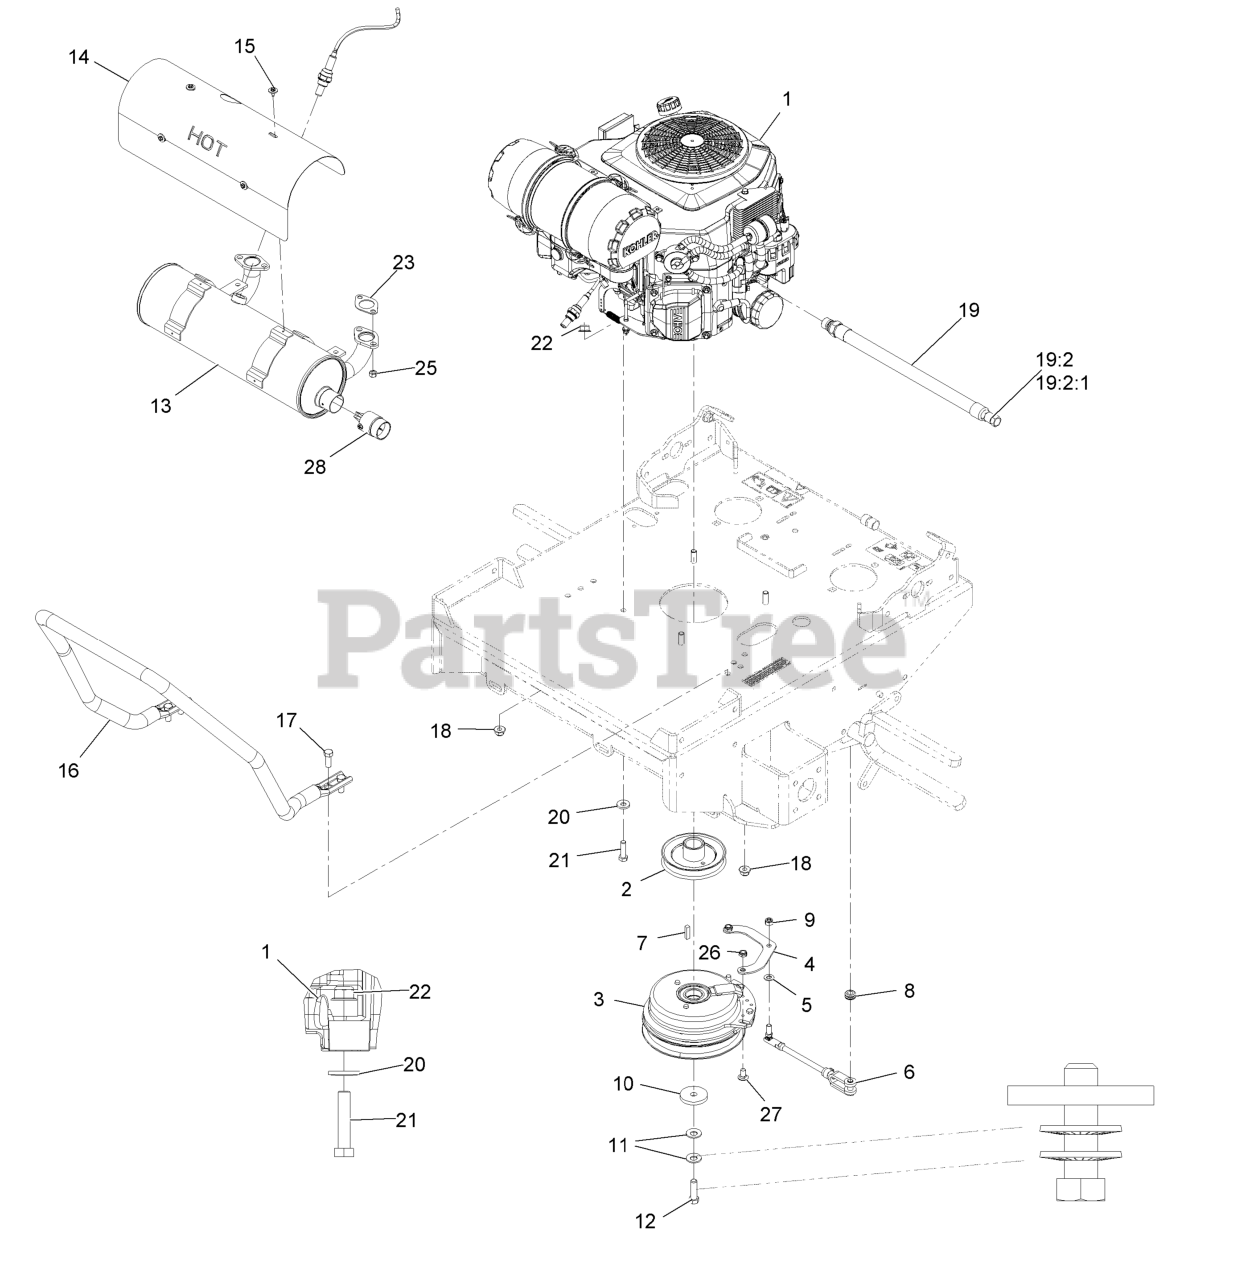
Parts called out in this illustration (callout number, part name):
2	Sheave W/ Hub
3	Clutch, 200 Ft/Lbs, 1.13
4	Strap, Clutch
5	Washer-5/16 SAE
6	ASM, Clutch Anchor
7	Key-Machine 1/4 X 1/4 X 1
8	Grommet
9	Nut-Lock 5/16-24
10	Washer-Clutch
11	Washer-Spring Disc 7/16
12	Bolt-Hex, TAP
13	Muffler-Ttx, Efi
14	Shield-Muffler,Ttx Efi
15	Screw-HH, Thread Forming
16	Guard,Air Cleaner
17	Screw-HH 3/8-16 X 1
18	Nut-Nyloc 3/8-16 Flg
19	Oil Drain Hose ASM
19:2	Plug-W/O-Ring
19:2:1	O-Ring
20	Washer-Spring Disc 5/16
21	Screw-HH 5/16-18 X 1 1/2
22	Nut-Nyloc 5/16-18 Flg
23	Gasket-Exhaust
25	Nut-Flange
26	Nut-Nyloc 5/16-18 Thin
27	Bolt-Carriage 5/16-18 X 5/8
28	Screen-Arrester, Spark
